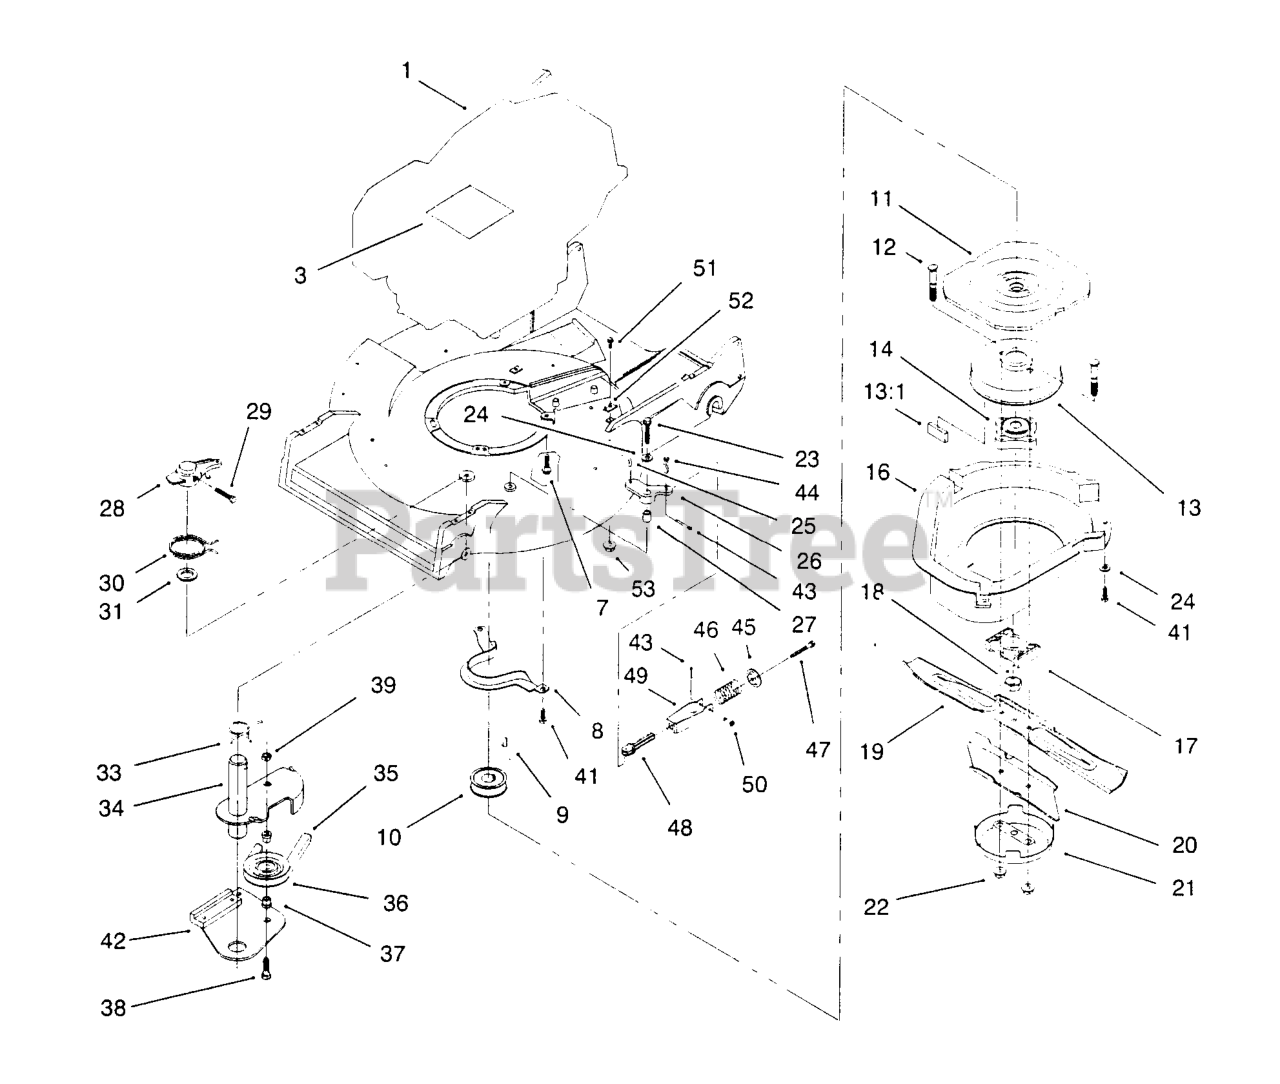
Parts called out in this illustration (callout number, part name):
1	Engine - Kawasaki
7	SCREW-MOUNT, ENGINE
8	BRACKET-GUIDE, BELT
9	KEY-WOODRUFF
10	PULLEY-DRIVER
12	BOLT-BLADE
13	BRAKE DRUM ASM
13:1	DAMPENER-VIBRATION
14	HUB ASM
18	NUT-LOCK, NI
20	STIFFENER-BLADE
21	CUP-SCALP, ANTI
22	Nut - Lock
23	SCREW-HH
24	WASHER-PLAIN
25	LINK-CONTROL
26	BELLCRANK
27	SLEEVE-BELLCRANK
29	SCREW-HH
30	SPRING-TORSION
33	SPRING-TORSION
34	ARM-IDLER
35	V-BELTNSP
37	SPACER-PULLEY, IDLER
38	SCREW-HH
39	NUT-LOCK, NI
41	Screw-HWH 5/16-18 X 3/4 Tf
43	PIN-COTTER
44	PIN-SPRING
45	RETAINER-SPRING
47	SCREW-HWHTF
49	BRACKET-SPRING
50	PIN-CABLE
51	SCREW-HH
52	CLAMP-CABLE
53	NUT-LOCK, NI
